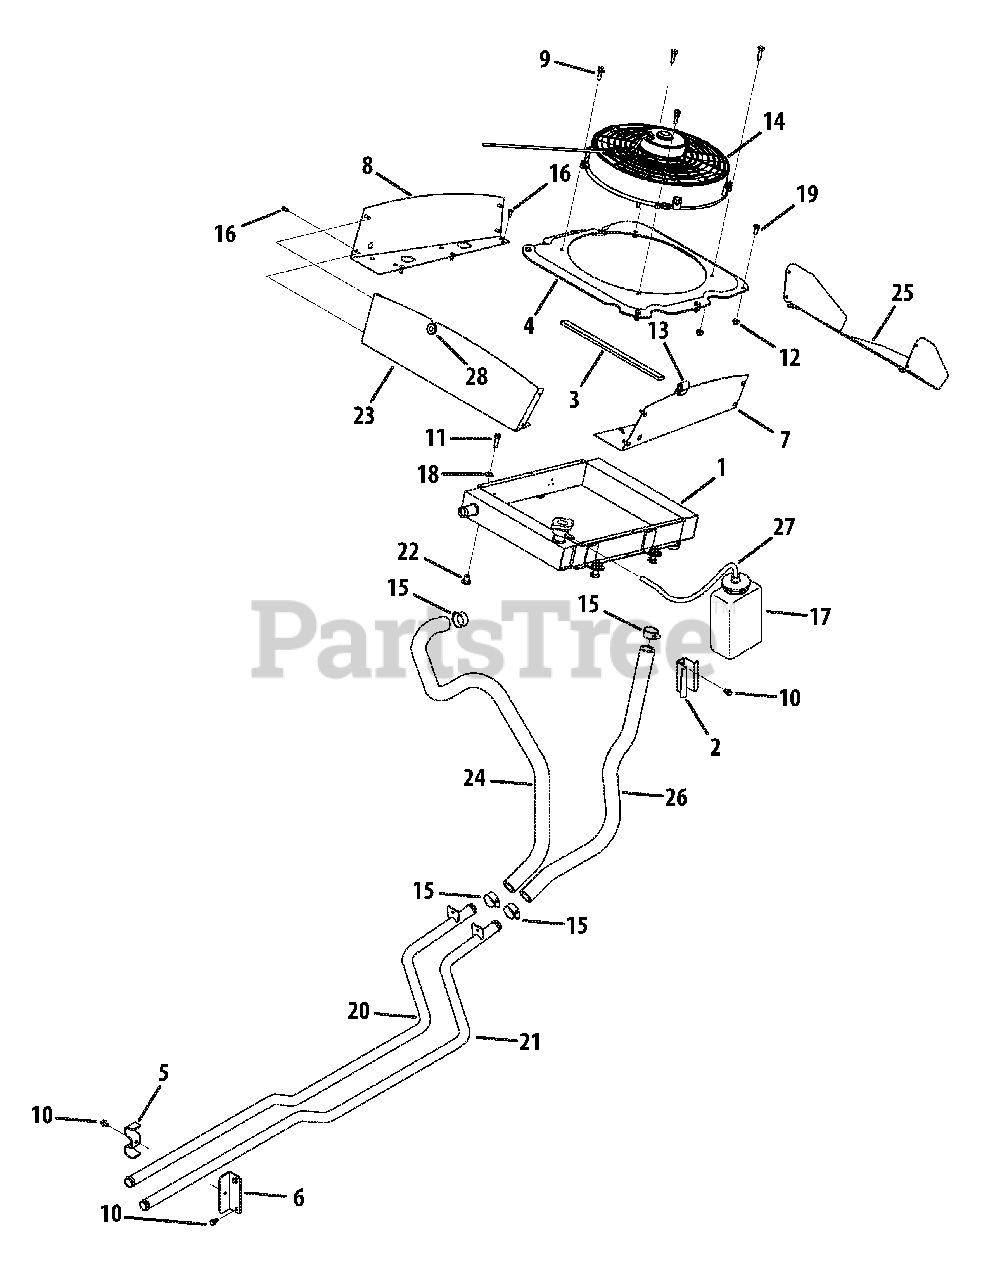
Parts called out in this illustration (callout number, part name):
1	Radiator Assembly, zin Core
2	Bracket, over Flow, bottle
3	Tape, .625 Wide x .25 Thk Foam
4	Shroud, Fan, Mount
5	Bracket, tube, uv
6	Bracket, rdtr Hose
9	Hex Head Screw, 1/4-20 x 1.00, gr5
10	Screw, tt, 1/4-20 x 0.500, hxindwsh
11	Screw, tt, 1/4-20 x 1.000, hxindwsh
12	Nut, Flange Lock, 1/4-20, Nylon
13	Heat Baffle Seal
14	Fan, electric, 12v, w/Guard, Yanmar
14	Fan, electric, 12v, w/Guard, Koh EFI
15	Clamp, hose, adj
16	Pop Rivet 3/16 Dia x .450, sty1
17	Container, overflow, coolant
18	Washer, flat, .28 x .74 x .063
19	Screw, 1/4-20 x .620
20	Tube, inside, rdtr 4x4
21	Tube, outside, rdtr 4x4
22	Spacer, Step
24	Hose, radiator, frt 4x4
25	Shroud, front
26	Hose, radiator, frt 4x4
27	Tube, overflow, radiator
28	Grommet, Rubber, Yan
28	Grommet, Rubber, Koh, EFI
